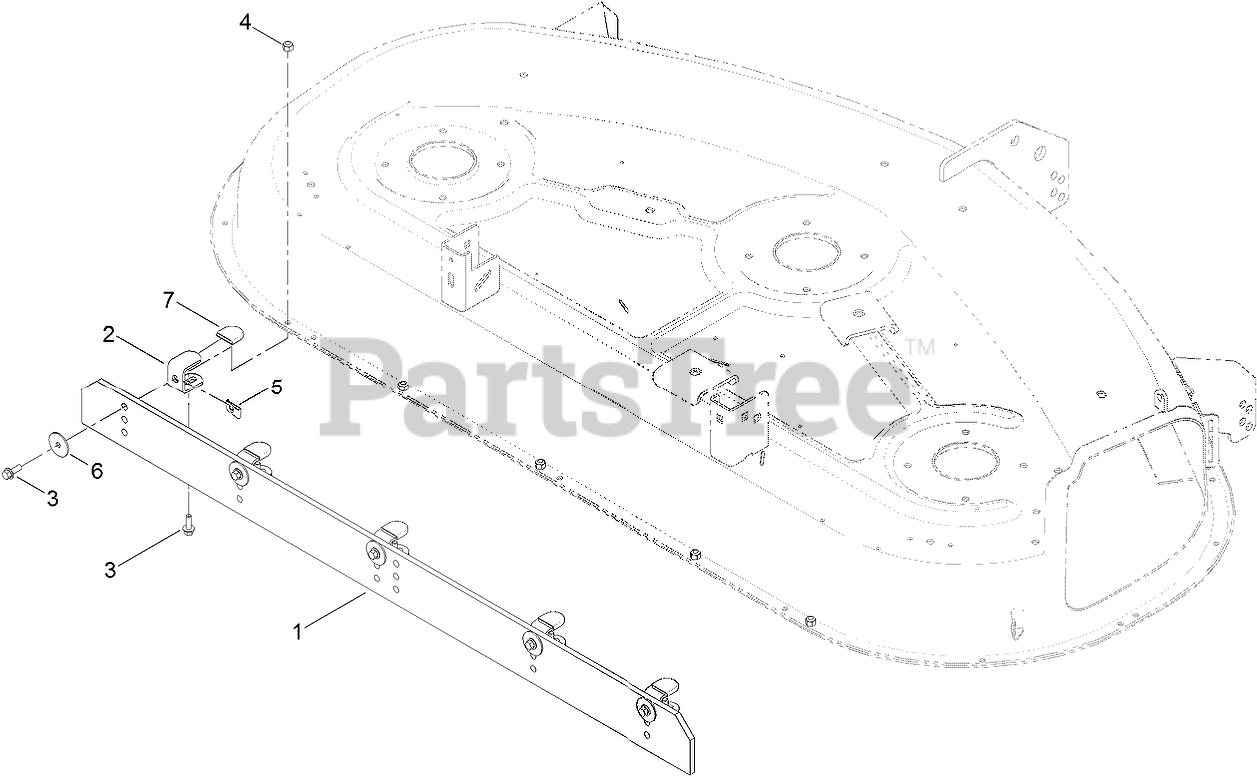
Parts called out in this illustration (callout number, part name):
1	WIPER-54 INCH
2	BRACKET-MOUNTING
3	SCREW-HHF
4	NUT-LOCK, NI
5	NUT-SPEED
6	WASHER-FLAT
